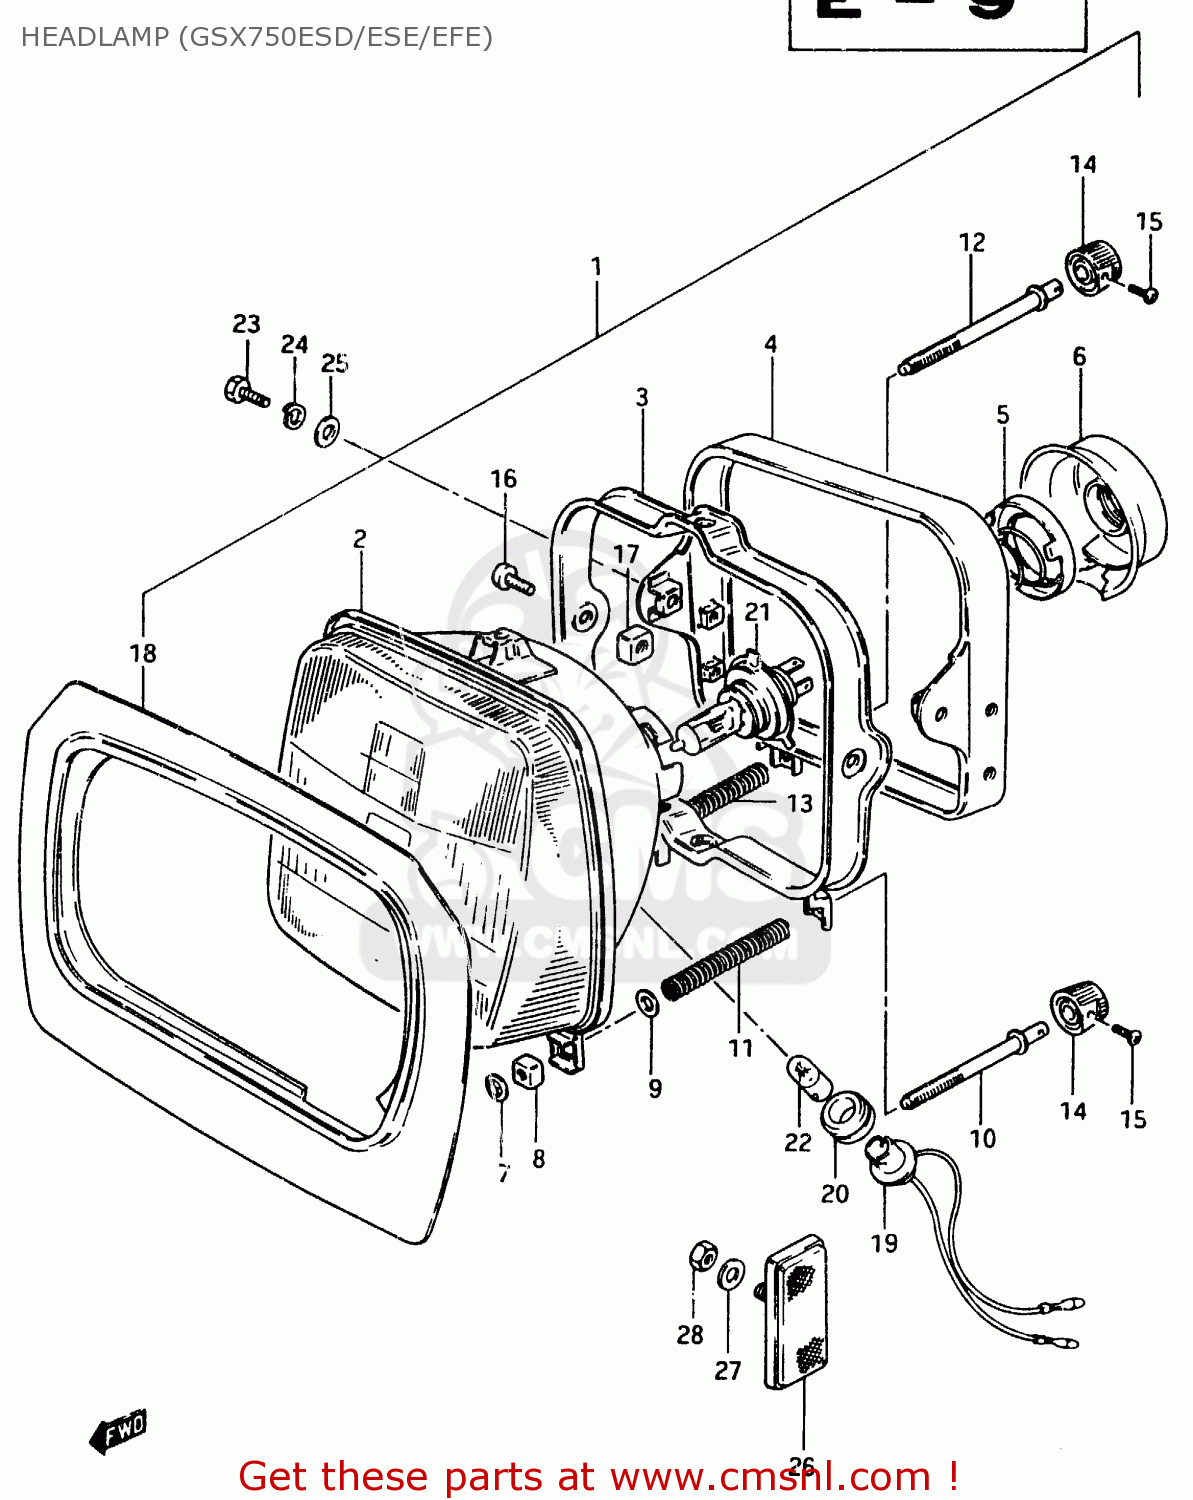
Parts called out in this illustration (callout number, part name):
1	HEADLAMP ASSY
2	UNIT
3	RING,MOUNTING
4	HOUSING,LAMP UNIT
5	HOLDER
6	COVER,HEADLAMP SOCKET
7	NUT,HEADLAMP ADJUSTER
8	NUT,HEADLAMP ADJUSTER
9	WASHER
10	SCREW,HEADLAMP ADJUST
11	SPRING
12	SCREW,ADJUSTING
13	SPRING
14	KNOB,ADJUSTER
15	SCREW
16	SCREW
17	NUT
18	SHADE
19	SOCKET
20	JOINT,RUBBER
21	BULB(12V60/55W,H4)
22	BULB(12V4W)
23	BOLT,M6X1X20
24	WASHER,LOCK
25	WASHER, LOWER
26	REFLEX REFLECTOR, FRONT SIDE
27	WASHER,5MM
28	NUT ,5MM
